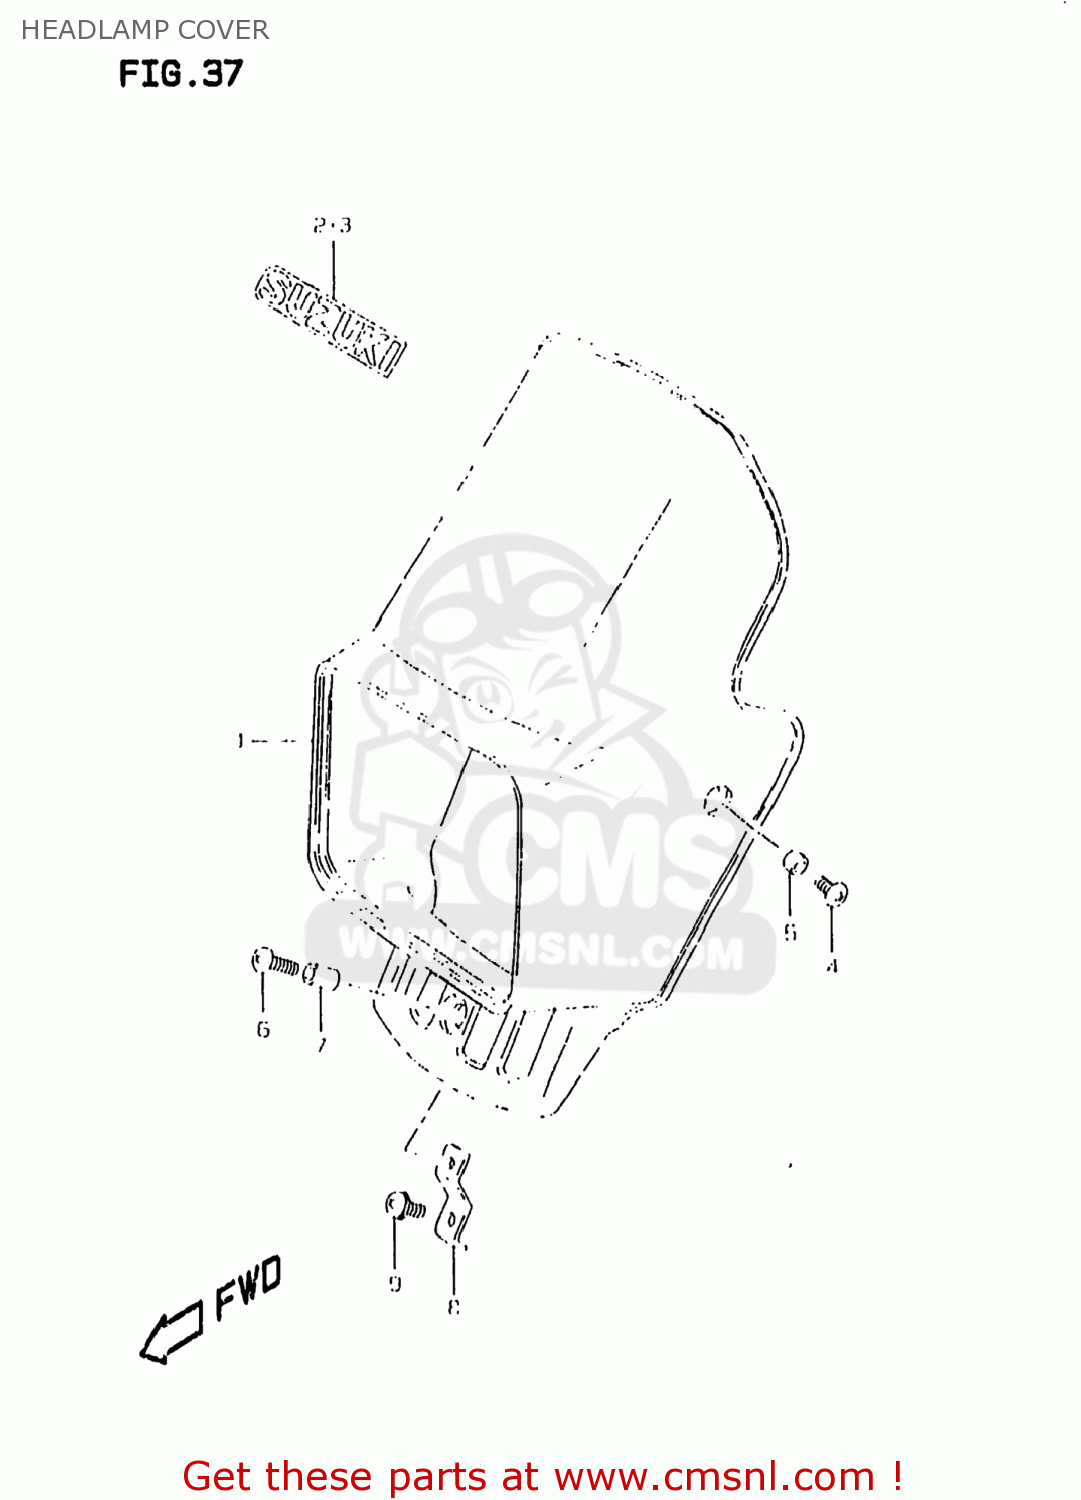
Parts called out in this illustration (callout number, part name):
1	COVER,HEADLAMP
2	EMBLEM,HEADLAMP COVER
3	EMBLEM
4	SCREW 6X12
5	SPACER(6.1X8X3.5)
6	SCREW
7	SPACER(6.1X8X12)
8	PLATE,HEADLAMP COVER
9	SCREW
